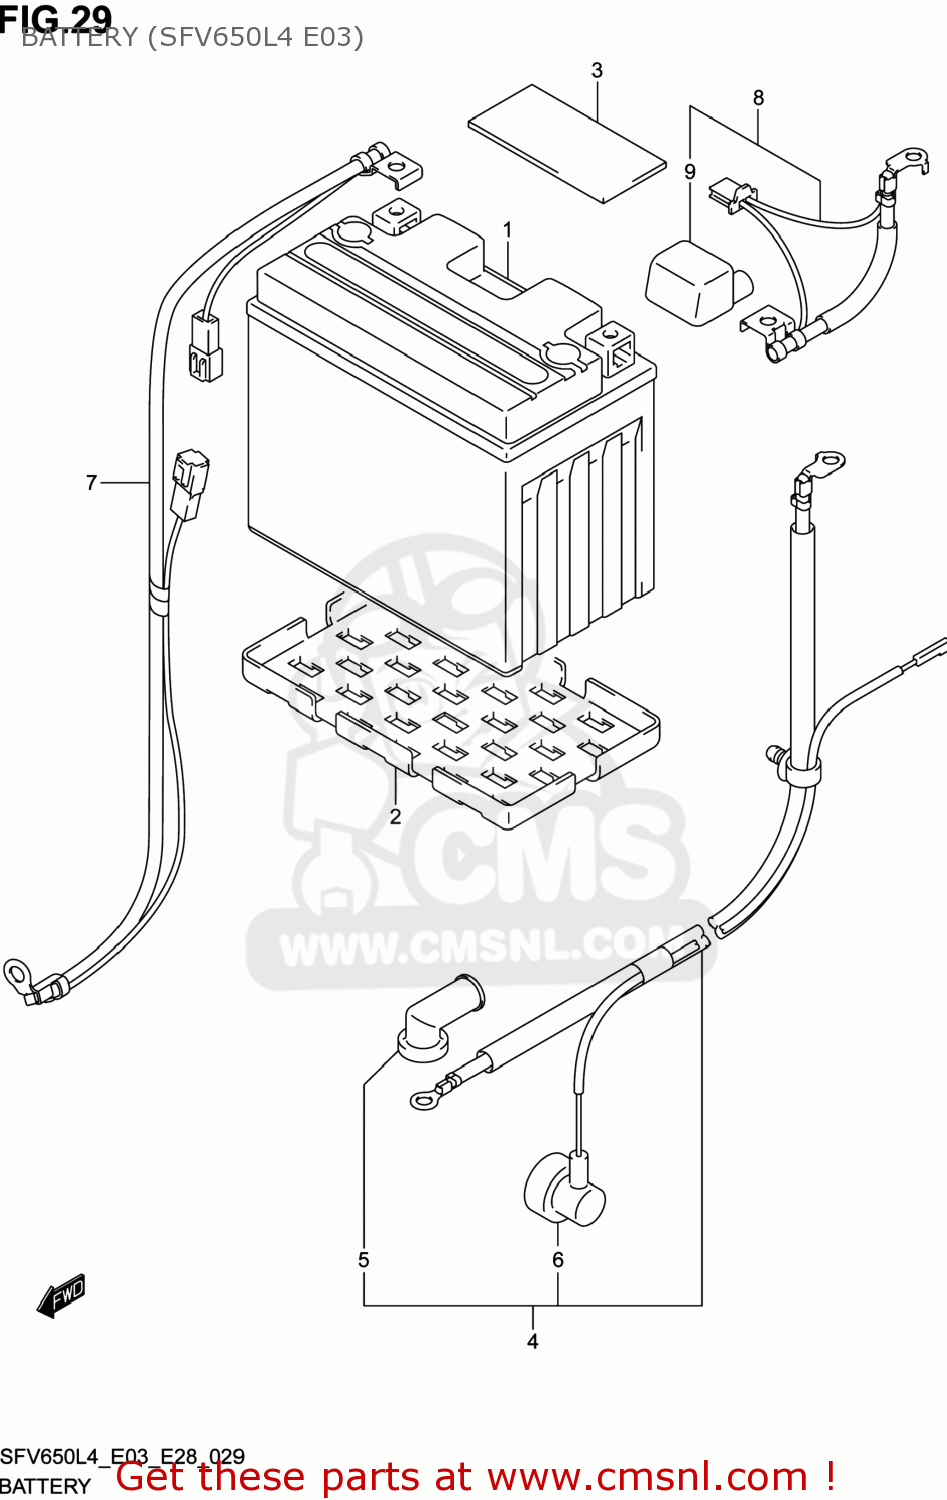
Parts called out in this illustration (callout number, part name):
1	BATTERY ASSY(FT12A-BS,12V10AH)
2	PROTECTOR,BATTERY
3	PROTECTOR
4	WIRE,STARTER MOTOR LEAD
5	CAP,STARTER MOTOR
6	CAP,OIL PRESSURE SWITCH
7	WIRE,BATTERY MINUS LEAD
8	WIRE,BATTERY PLUS LEAD
9	CAP,BATTERY PLUS
